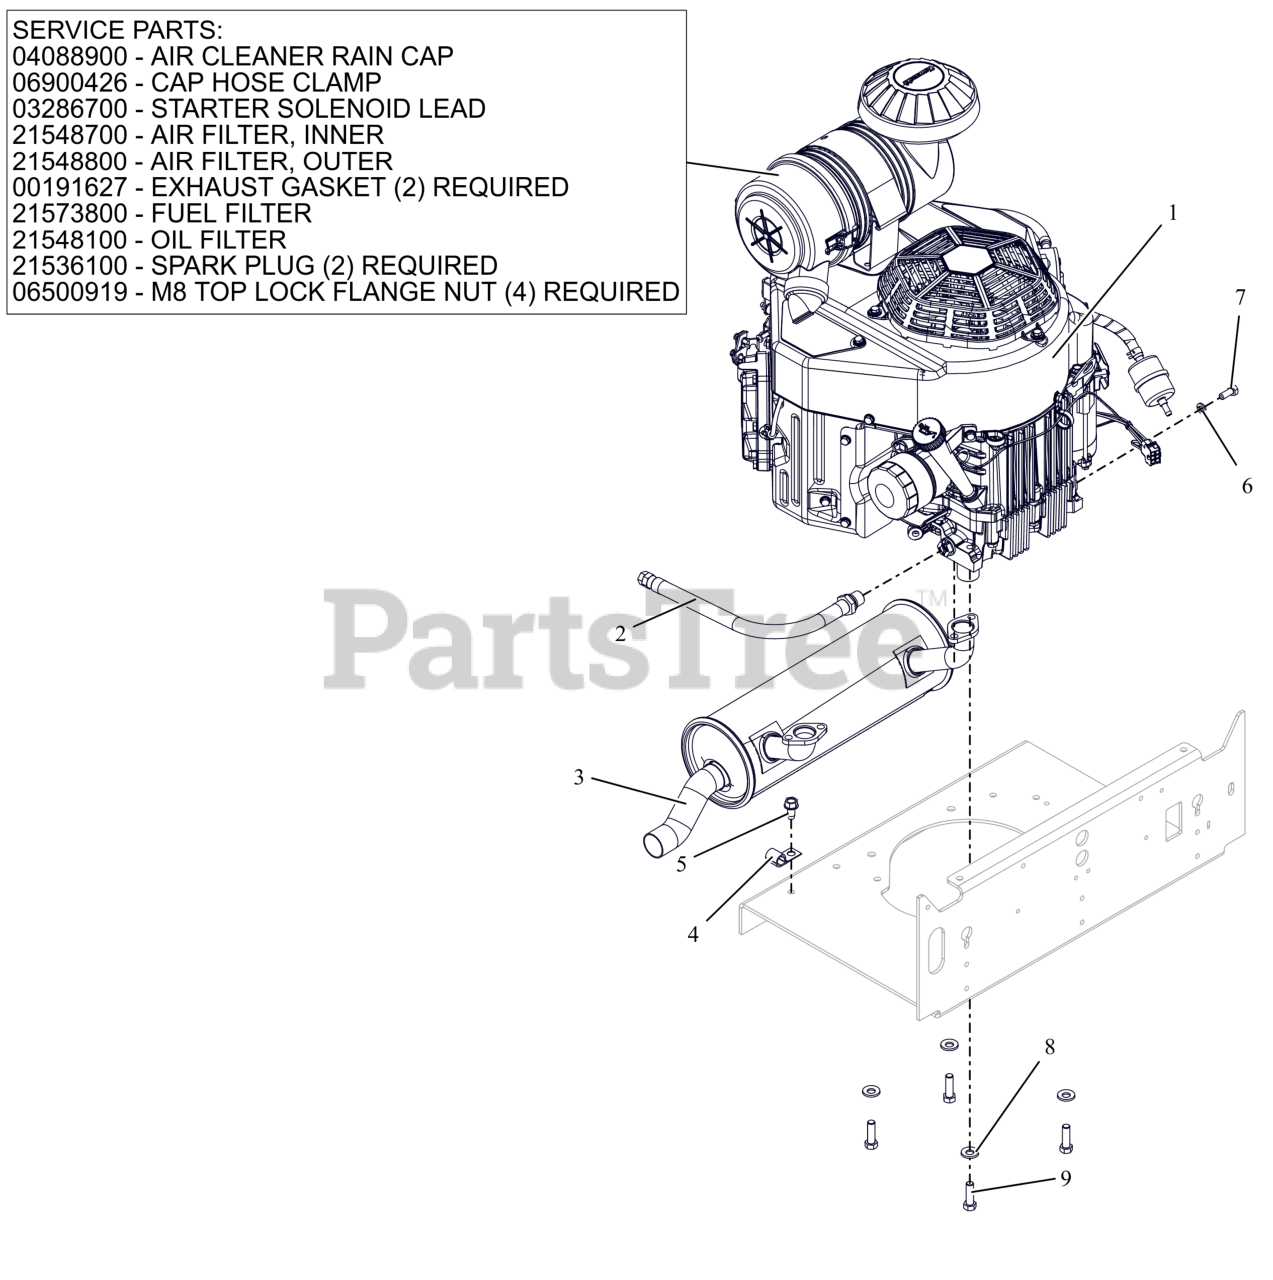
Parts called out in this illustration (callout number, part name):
1	ENGINE, KAWASAKI FW691
1	CAP, KAW 11065-7025
1	CLAMP, HOSE #36 SS 1.813-2.75
1	LEAD - STARTER SOLENOID
1	FILTER, OUTER
1	FILTER, INNER - KAW
1	OIL FILTER, KAWASAKI FR
1	FUEL FILTER
1	PLUG, SPARK
1	GASKET, MUFFLER S/O
1	NUT-LK-TOP-FLG M8 ZCC
2	HOSE, OIL DRAIN
3	MUFFLER, KAW FX691/730
5	SCR,TAP .375-16X.75 HWH TR ZCC
6	WSHR,LK-REG .312X.078 ZCC
7	BLT, HEX M8-1.25X20 G8.8 ZCC
8	WASHER, 3/8" SPRING DISC
9	BLT, HEX .38-16X1.25 G5 ZCC NT
